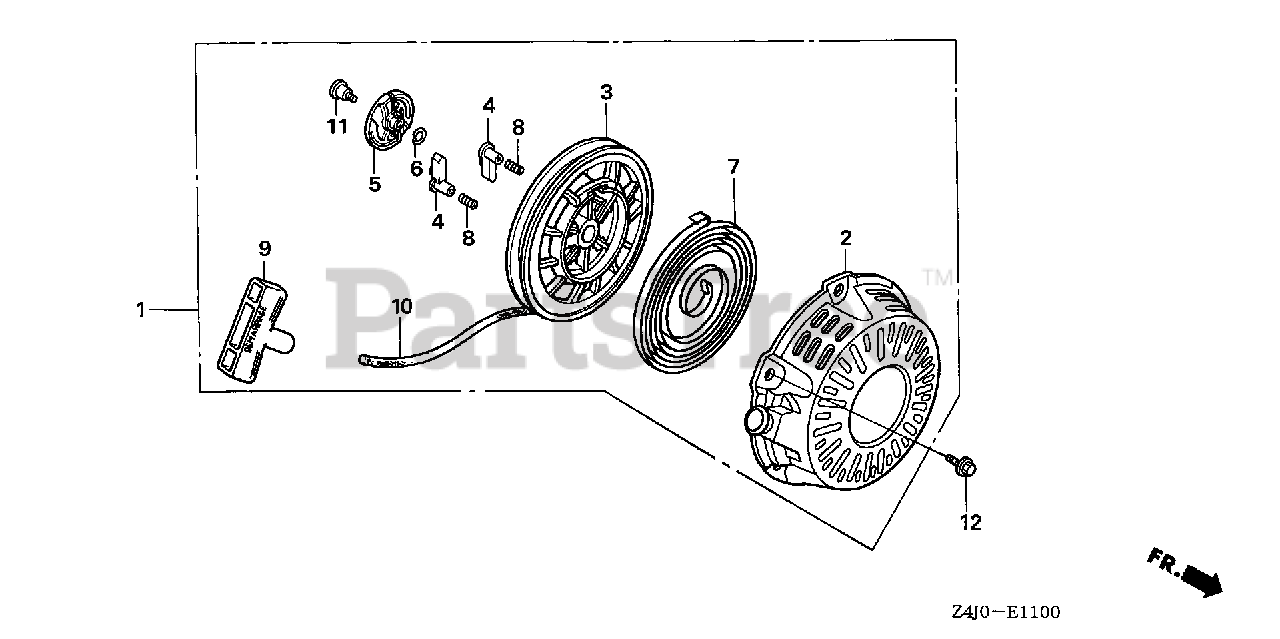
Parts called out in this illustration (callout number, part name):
1	STARTER ASSY., RECOIL *NH105* (MAT BLACK)
2	CASE, RECOIL STARTER *NH105* (MAT BLACK)
3	REEL, RECOIL STARTER (NATURAL)
4	RATCHET, STARTER
5	GUIDE, RATCHET
6	SPRING, FRICTION
7	SPRING, RECOIL STARTER
8	SPRING, RETURN
9	KNOB, RECOIL STARTER
10	ROPE, RECOIL STARTER
11	SCREW, SETTING
12	BOLT, FLANGE (6X10)
